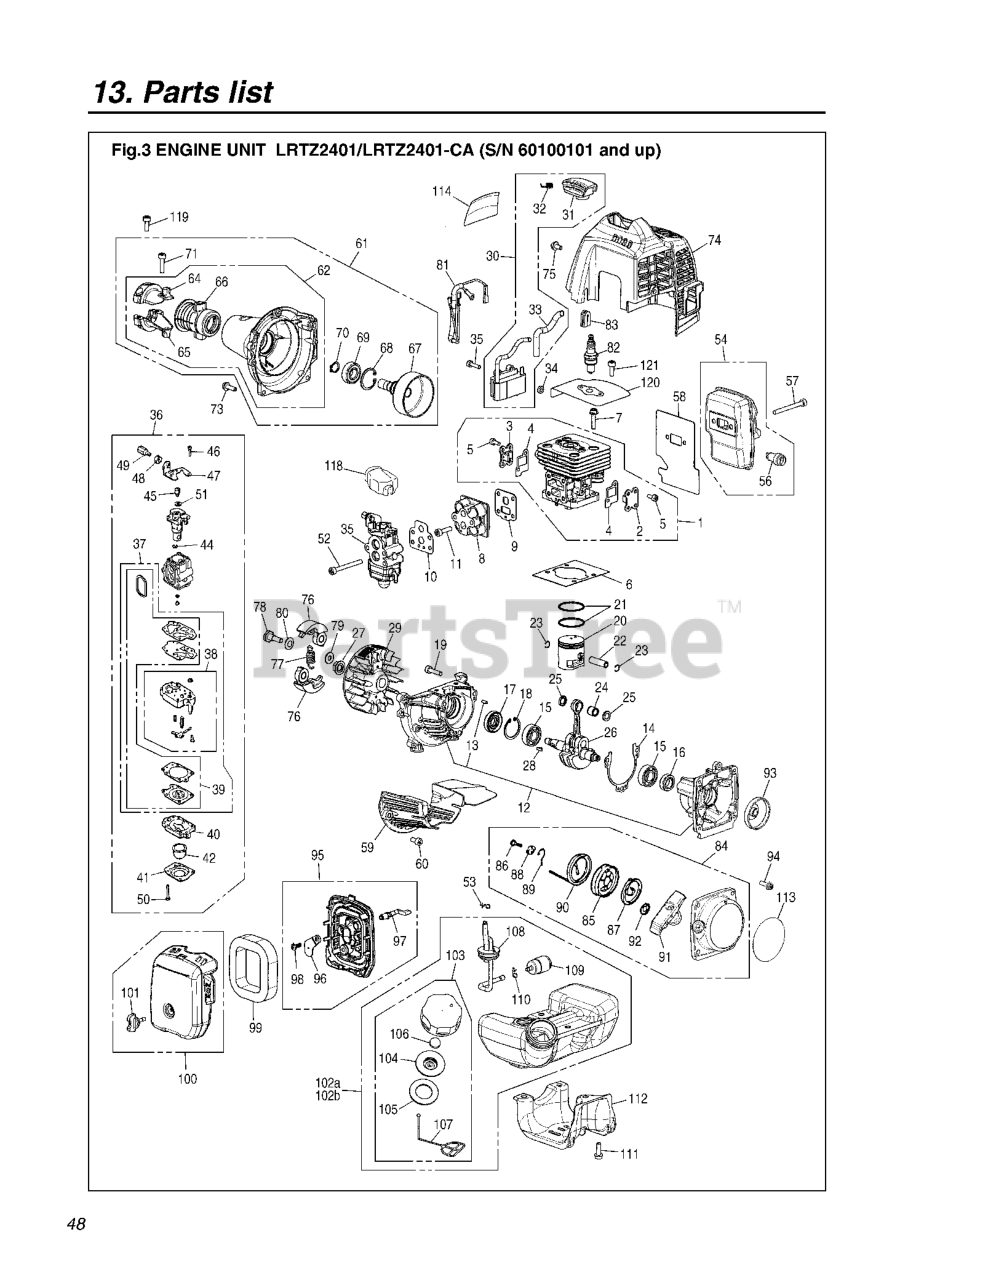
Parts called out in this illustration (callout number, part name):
1	CYLINDER COMPLETE
2	COVER, TR-S
3	COVER, TR-F
4	GASKET, TR
5	BOLT
6	GASKET, BASE
7	BOLT
8	INSULATOR
9	INSULATOR GASKET(R-848F0814B0)
10	GASKET, CARB
11	BOLT TORX
12	CRANKCASE-C
13	PIN
14	GASKET, CASE
17	SEAL
22	PIN
26	CRANKSHAFT-C
27	NUT
28	KEY
30	COIL ASSY
31	CAP
34	SPACER
36	CARBURETOR (RPLS 848F088100)
37	REBUILD KIT
38	CARBURETOR BODY
39	GASKET KIT
41	1OVER
44	RING
45	SWIVEL
46	SCREW
47	BRACKET
48	NUT
49	ADJUSTER
51	WASHER
53	CLIP
54	MUFFLER-A***
56	ARRESTER
58	GASKET, MUFFLER
61	HOUSING ASSY (RPLS T155131000)
62	HOUSING
64	BRACKET (A) (RPLS T170031211)
65	BRACKET (B)
67	DRUM (RPLS 481031120-22)
69	BEARING
74	COVER, ENGINE
75	BOLT (RPLS T495051010-11)
81	CORD-COMP
82	PLUG CMR7H
84	RECOIL ASSY
87	SPRING, SPIRAL
88	COLLAR
89	SWING ARM
92	PLATE.STOPPER
95	BODY ASSY
96	PLATE.CHOKE
97	LEVER CHOKE
98	SCREW
100	COVER-A (RPLS T155182200)
102A	TANK ASSY (RPLS T155185001)
103	CAP A
104	HOLDER-A
108	PIPE-C
109	FILTER ASSY
110	CLIP
114	LABEL COVER
